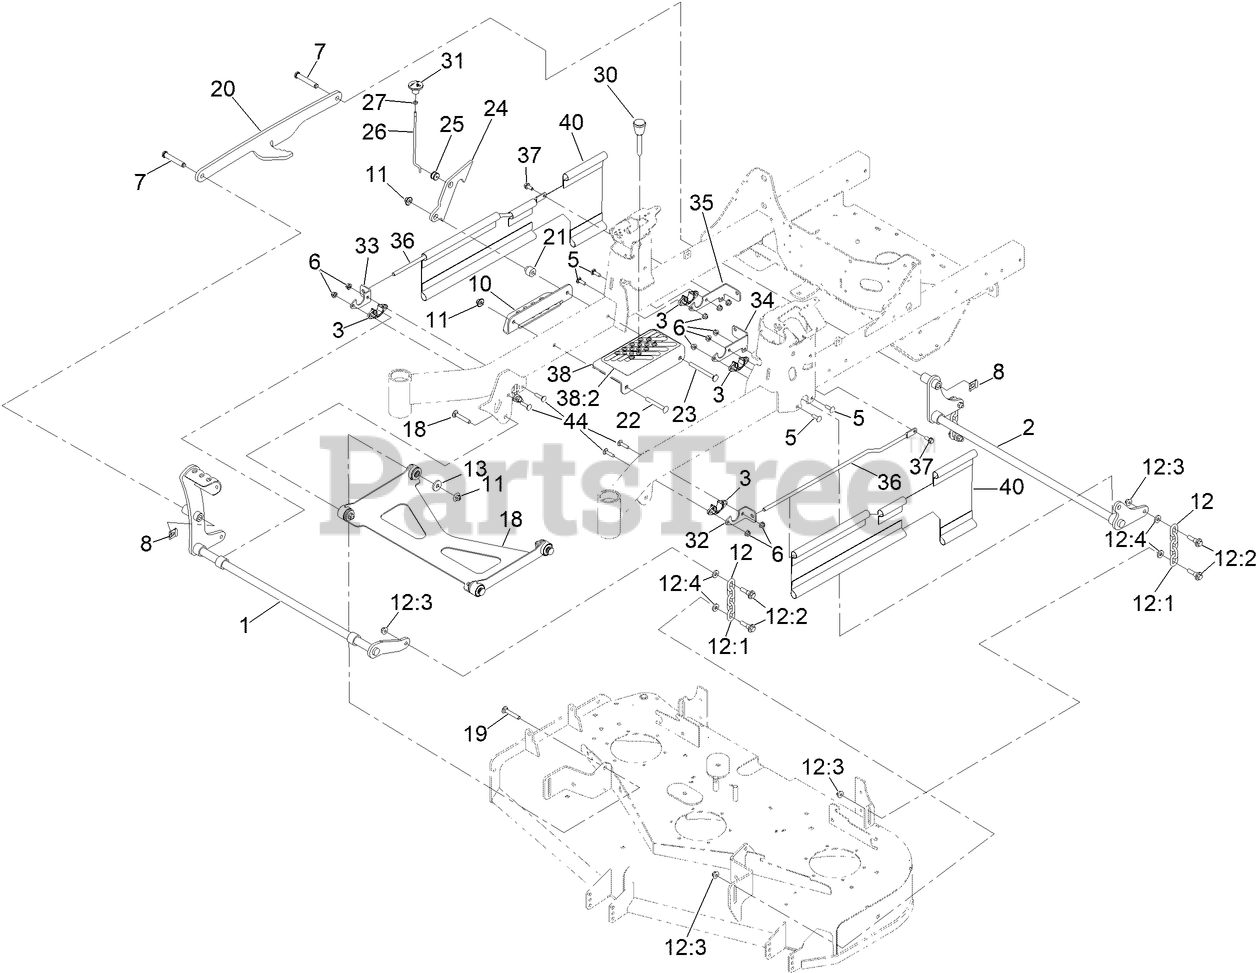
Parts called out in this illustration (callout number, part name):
1	SHAFT-LIFT, DECK
2	SHAFT-LIFT, DECK (REAR)
3	BEARING-FLANGE
5	SCREW-CARR
6	NUT-HF, NI
7	PIN-CLEVIS
8	CLIP-PIN
10	ANGLE-HOC, LOWER
11	NUT-FLANGE, NI
12	DECK CHAIN ASM
12:1	CHAIN-LIFT, DECK
12:2	BOLT-SHOULDER
12:3	NUT-HF, NI
12:4	SPACER
13	WASHER
18	DECK STRUT ASM
19	SCREW-CARR
20	LINK-LIFT
21	SPACER-STEPPED
22	SCREW-CARR
23	SCREW-CARR
24	PLATE-LOCK, TRANSPORT
25	GROMMET
26	ROD-LOCK, TRANSPORT
27	NUT-JAM
30	PIN-HOC
32	BRACKET-MOUNT, FRONT (LH)
33	BRACKET-MOUNT, FRONT (RH)
34	BRACKET-MOUNT, UPPER REAR (LH)
35	BRACKET-MOUNT, UPPER REAR (RH)
36	ROD-SUPPORT, UPPER
37	SCREW-HHF
38	HOC PLATE W/DECAL
38:2	DECAL-HOC
40	GUARD-SIDE
44	SCREW-CARR
